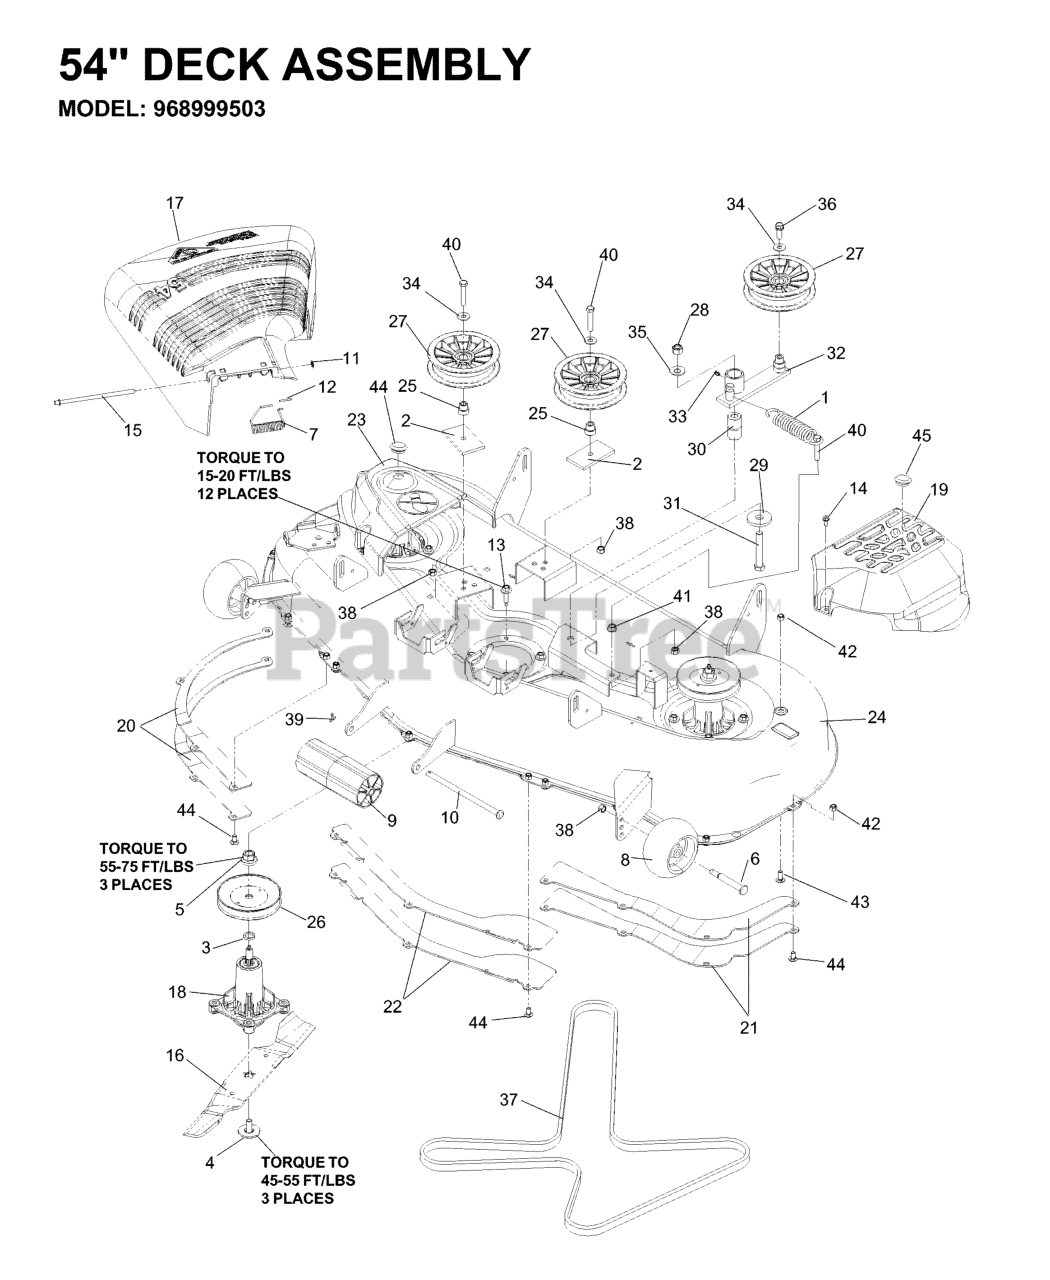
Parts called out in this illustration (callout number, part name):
2	SUPPORT PLATE
3	WASHER-SPACER
4	BLADE BOLT ASSY-7/16" TB REPL
5	LOCKNUT - 9/16
6	SHOULDER BOLT 1/2X2-5/8 ZD SPE
7	TORSION SPRING
8	GAUGE WHEEL
9	NOSE ROLLER-48"
10	NOSE ROLLER ROD
11	PUSH NUT
12	CAP-SLEEVE
13	WASHER HEAD SCREW
14	SCREW- 1/4-20 X 5/8
15	ROD, HINGE
16	BLADE STANDARD 54
17	DEFLECTOR, 54"
18	MANDREL GREASABLE
19	COVER, MANDREL, LEFT, 54"
20	BAFFLE, RIGHT 54"
21	BAFFLE LEFT 54
22	BAFFLE, CENTER, 54"
23	COVER, MANDREL, RIGHT, 54"
24	DECK W/DECALS 54" HUS
25	IDLER BUSHING
26	PULLEY
27	IDLER
28	NUT 1/2-13 HEX NYLOC ZD
29	WASHER, SUPPORT
30	PIVOT BUSHING
31	HCS 1/2C X 3 1/4
33	ZERK
34	WASHER 3/8 FLAT
35	WASHER 1/2 FLAT
36	4CS 3/8C X 1 SERRATED HEAD
38	NUT 3/8-16 NYLOC
39	RP_COTTER PIN 1/8 X 3/4
40	HCS 3/8C X 2
41	NUT 3/8C WHIZ
42	NUT 5/16 NYLOC
43	CARRIAGE BOLT 5/16C X 5/8"
44	RHSNB 5/16C X 1
45	PLUG, BUTTON HOLE
